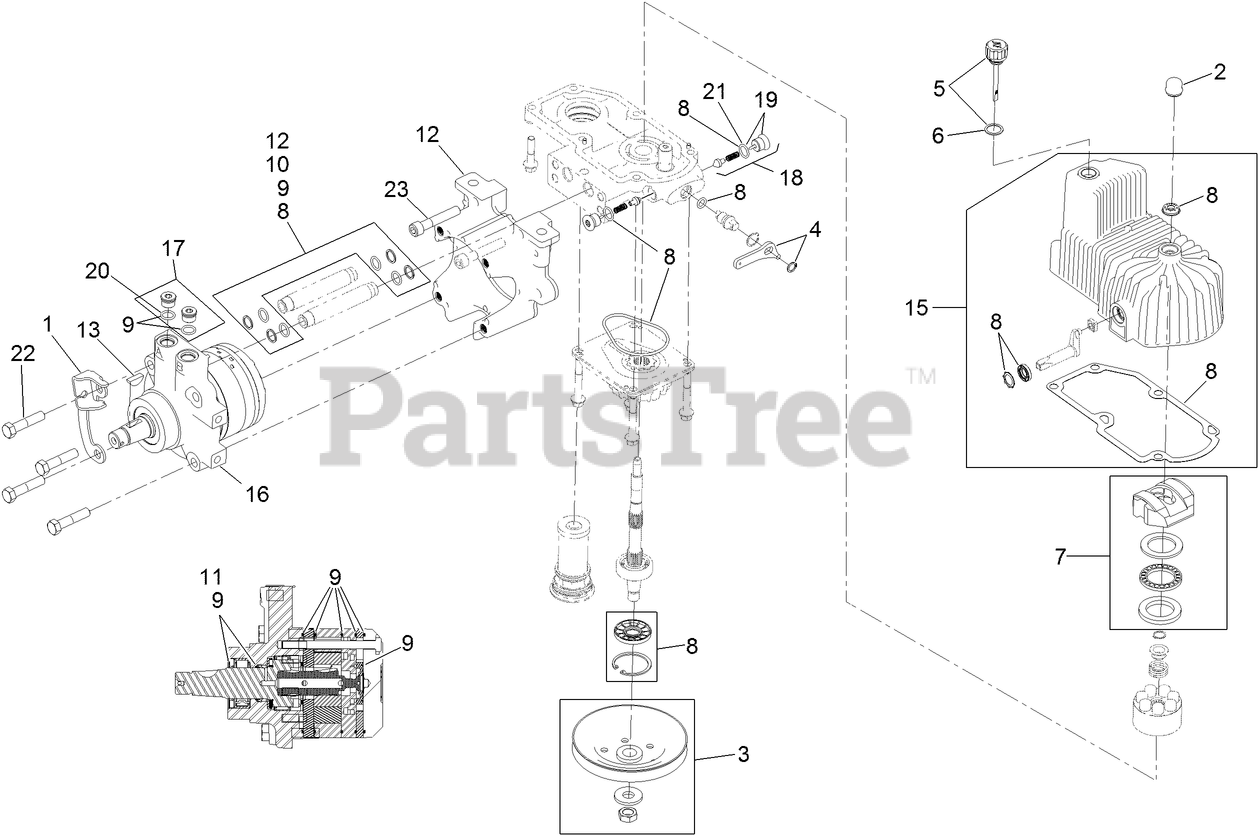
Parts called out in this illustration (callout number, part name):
1	BRACKET-ANCHOR, CABLE
2	COVER-SHAFT, HYDRO
3	PULLEY KIT
4	HANDLE-BYPASS VALVE, HYDRO
5	DIPSTICK-HYDRO W/GASKET
6	GASKET-DIPSTICK, HYDRO
7	SWASH BLOCK KIT
8	PUMP SEAL KIT
9	MOTOR SEAL KIT
10	TUBE SEAL KIT
11	OUTPUT SHAFT SEAL KIT
12	NOSE CUP-UHT
13	KEY-WOODRUFF
15	HOUSING-HYDRO, LH
16	MOTOR-HYDRAULIC LH 240CC
17	MAGNETIC PLUGS SERVICE KIT
18	CHECK VALVE ASM
19	PLUG-CHECK (W/O-RING)
20	O-RING
21	O-RING-CHECK VALVE
22	SCREW HH
23	SCREW-HSH
